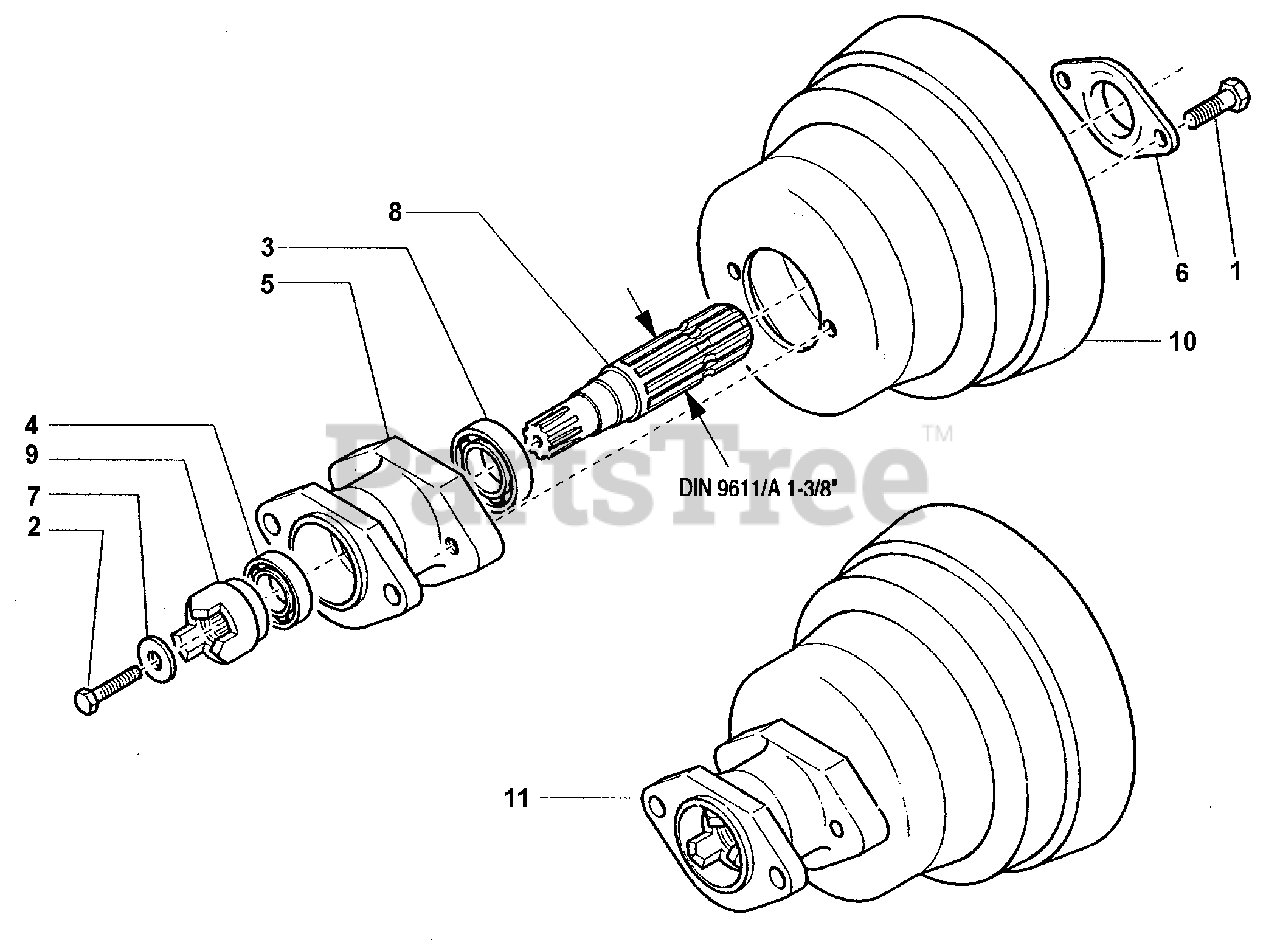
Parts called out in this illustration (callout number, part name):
1	SCREW, M6 X 20
2	SCREW M12 X 45
3	NUT, SELF LOCKING M12
4	WASHER, LOCK M12
5	CIRCLIP, INTERNAL
6	BEARING M25 X 47 X 12
7	BUSHING FOR QUICK HITCH
8	TANG CASE FOR QUICK HITCH
11	EXTENSION RING
13	RING FOR COUPLER
16	3-DOG COUPLING
18	QUICK HITCH ASSEMBLY
19	QUICK HITCH TANG
20	QUICK HITCH BUSHING
22	GRIP FOR LEVER (NOT PICTURED)
